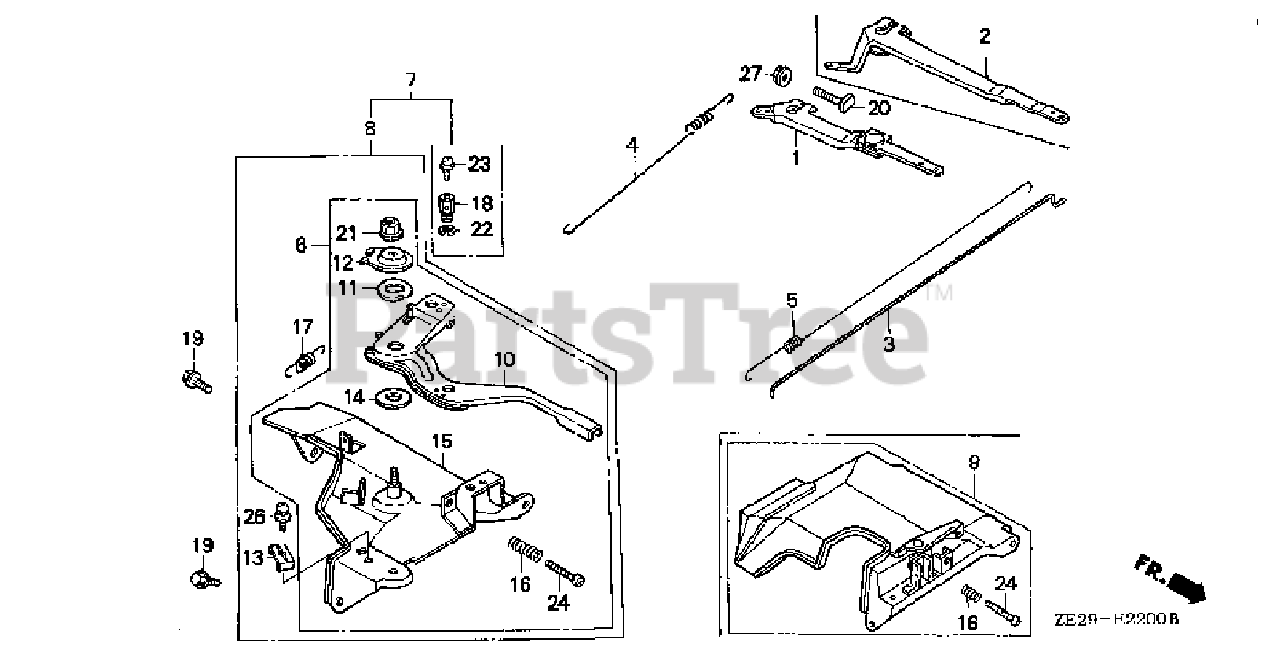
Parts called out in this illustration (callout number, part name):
2	ARM, GOVERNOR
3	ROD, GOVERNOR
4	SPRING, GOVERNOR
5	SPRING, THROTTLE RETURN
8	CONTROL ASSY. (REMOTE)
10	LEVER, CONTROL
11	SPRING, LEVER
12	WASHER, CONTROL LEVER
13	HOLDER, CABLE
14	SPACER, CONTROL LEVER
15	BASE, CONTROL
16	SPRING, CONTROL ADJUSTING
17	SPRING, CABLE RETURN
19	BOLT, FLANGE (6X12) (CT200)
20	BOLT, GOVERNOR ARM
21	NUT, SELF-LOCK (6MM)
24	SCREW, PAN (5X28)
26	SCREW, PAN (5X16)
27	NUT, FLANGE (6MM)
